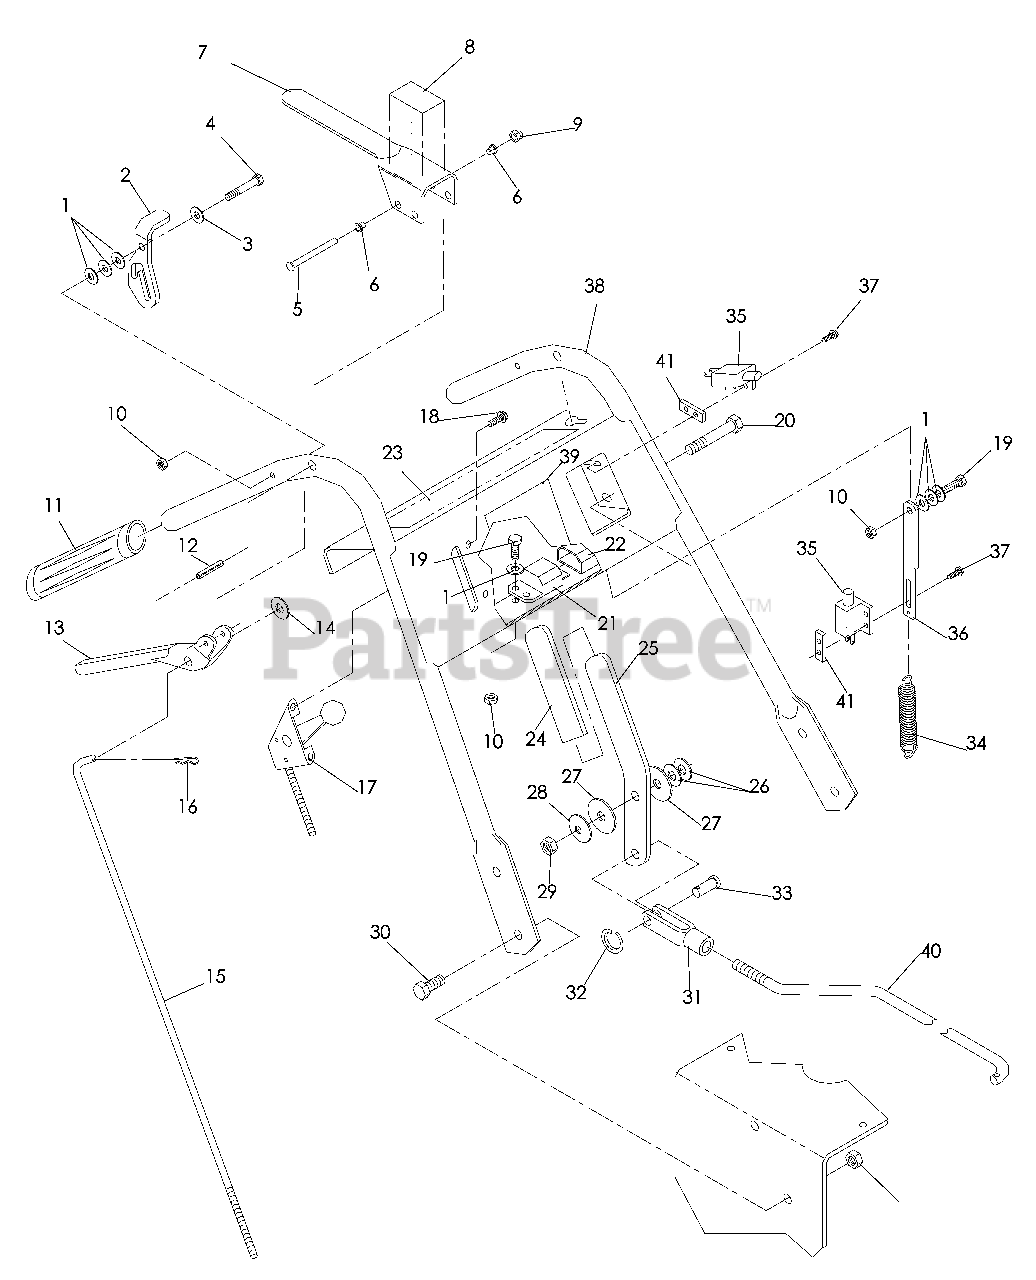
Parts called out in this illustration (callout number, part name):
1	WASHER¼, SAE
2	LATCH, LT W/GRIP
3	LATCH, RT W/GRIP
4	WASHER, WAVE SPRING
5	HCS ¼-20 x 1¾
6	PIN, CLEVIS
8	LEVER, OP W/GRIP
9	DECAL, THUMB LATCH
11	NUT ¼-20 CENTERLOCK
12	GRIP HANDLE
13	ROLL PIN 5/16 x 11/8
14	LEVER, MOLDED DRIVE
15	WASHER 5/16
16	TRACTION ROD
17	COTTER HAIRPIN, #2
18	THROTTLE CNTRL W/BALL MODEL 968999278
19	SCREW ¼-20 x 3/8 SELF TAP
20	HCS ¼-20 x ¾
21	HCS 3/8-16 x 1½
23	HANDLE HARNESS MODEL 968999278
24	DECAL, OPERATION
27	WASHER 3/8
28	FIBER WASHER
29	CONE WASHER
30	NUT 3/8-16 CENTERLOCK
31	HCS 3/8-16 x 1
33	RETAINER, RING
34	CLEVIS PIN
37	OP LINKAGE
38	SCREW, #10-24 x 5/8
39	UPPER HANDLE W/DECALS
40	DECAL, OPERATION
42	TAPPED PLATE
